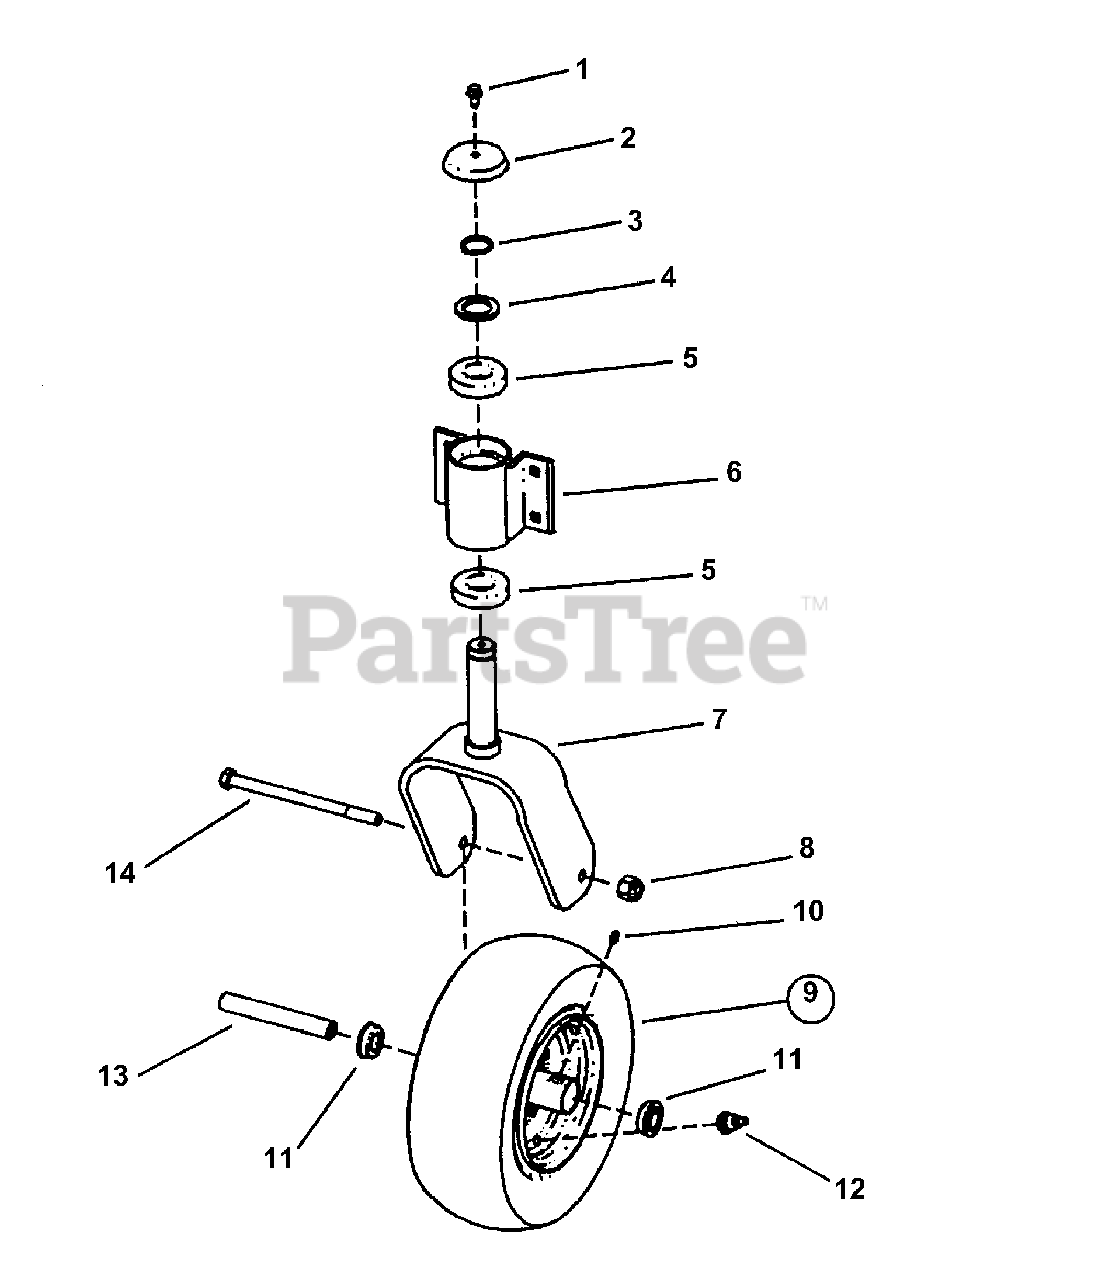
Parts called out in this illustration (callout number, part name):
1	SCREW, 5/16-18 x 5/8" Hex Flange Self Tap
2	CAP, Caster Shaft
3	RING, 1-3/16" External Retaining
4	WASHER, 1-1/4" Flat
5	BEARING, 30mm x 62mm
6	WELDMENT, Caster Support
7	WELDMENT, Caster Yoke
8	NUT, 1/2-13 Hex Nyloc
9	ASSEMBLY, Tire & Rim
10	FITTING, Lube
11	BEARING
12	VALVE, Air
13	SLEEVE, Axle
14	BOLT, HEX, 1/2-13 X 7, GD 8, YZ
